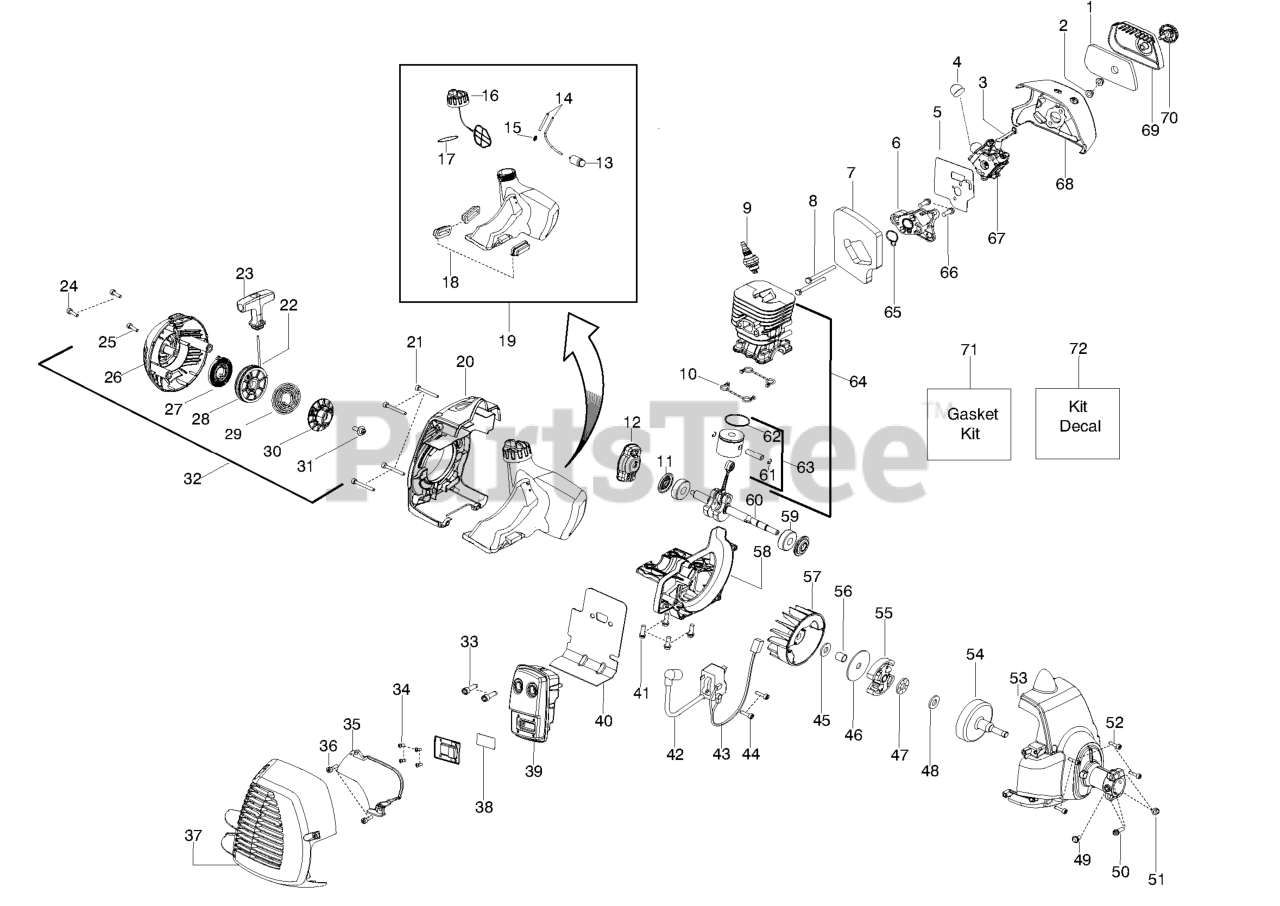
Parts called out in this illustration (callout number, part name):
1	FILTER AIRBOX
3	CHOKE LEVER
4	PURGE BULB ZAMA
5	KIT GASKET CARB 28CC
6	CARB ADAPTOR
7	KIT GASKET 28CC
8	BOLT CARB ADAPTOR
9	Plug - Spark (RCJ-8Y)
10	KIT GASKET 28CC
11	KIT GASKET 28CC
12	STARTER PAWL BRIDGE
13	FUEL PICK-UP ASSY
14	KIT-LINE(FUEL)
15	FUEL LINE FITTING
16	ASSY-CAP W/RETAINER
17	KIT GASKET 28CC
18	ISOLATOR FUEL TANK
19	KIT FUEL TANK HVA
20	KIT STARTER HSG HVA 128
22	KIT ROPE
23	HANDLE - STARTER
24	SCREW M5-0.8X30MM
25	SCREW M4 X 1.75 PT 16MM
26	KIT STARTER HSG HVA 128
27	KIT STARTER SPRING
28	KIT STARTER PULLEY
29	SPRING - DRIVER
30	DRIVER PULLEY
32	ASSY STARTER HSG HVA
33	BOLT MUFFLER
34	SCREW-6-19X5/16PLAST PA
35	SHIELD HEAT
36	SCREW M4 X 1.75 PT 16MM
37	KIT MUFFLER GUARD HVA
38	KIT SPARK ARRESTOR SCREEN
39	KIT MUFFLER LE28
40	KIT GASKET 28CC
41	SCREW-M5-0.8 X 25MM(TAP)
42	IGNITION MODULE MBU-7
43	ASSY MODULE LEAD WIRE
44	SCREW M4 X .70 TT 16MM
45	WASHER CLUTCH
46	WASHER-CLUTCH
47	BEARING THRUST
48	WASHER THRUST
49	Screw
50	Screw
51	LOCKNUT-HEX 10-24
52	SCREW M4 X .70 TT 16MM
53	Assy - Fan Housing
54	ASSY-CLUTCH DRUM
55	ASSEMBLY CLUTCH
56	SPACER FLYWHEEL
58	CRANKCASE CAST LE28
59	BEARING RADIAL BALL (6201)
60	ASSY CRANKSHAFT
61	WRIST PIN RET.
62	RING PISTON
63	KIT - PISTON
64	KIT PISTON CYL
65	KIT GASKET 28CC
66	SCREW-M5-0.8 X 25MM(TAP)
67	KIT CARB
68	RP_AIR BOX
69	COVER-AIR BOX
70	KNOB ASSY AIRBOX COVER
71	KIT GASKET 28CC
